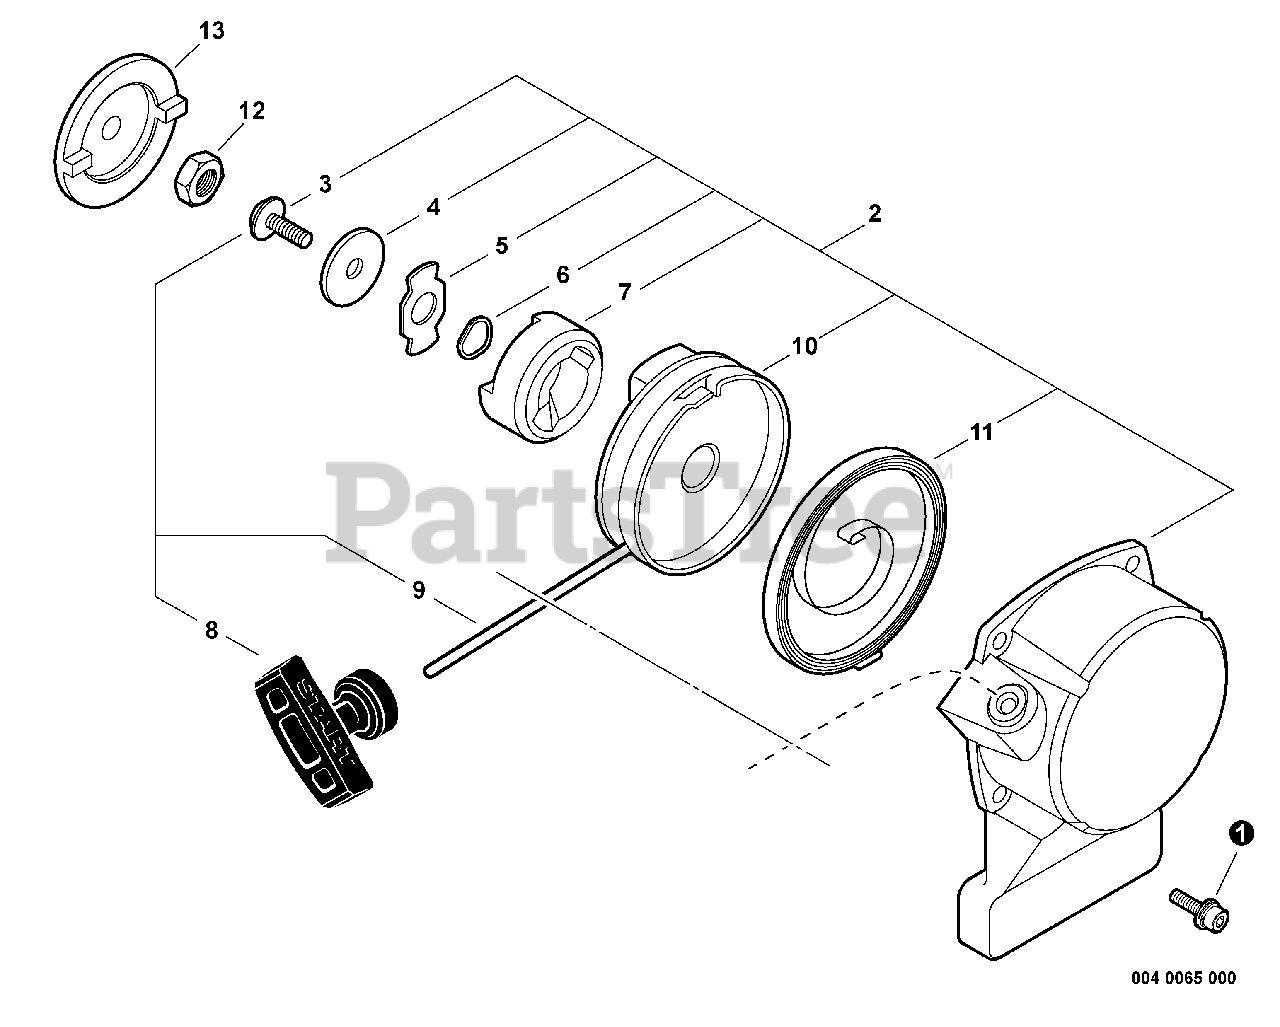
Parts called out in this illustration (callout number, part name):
1	SCREW - 4X12
2	STARTER ASSY
3	SCREW - 5
4	WASHER - 5
5	RETAINER
6	WASHER - SPRING
7	CATCHER, PAWL
8	GRIP, STARTER
9	ROPE, STARTER
10	REEL, ROPE
11	SPRING, REWIND
13	PAWL, STARTER
